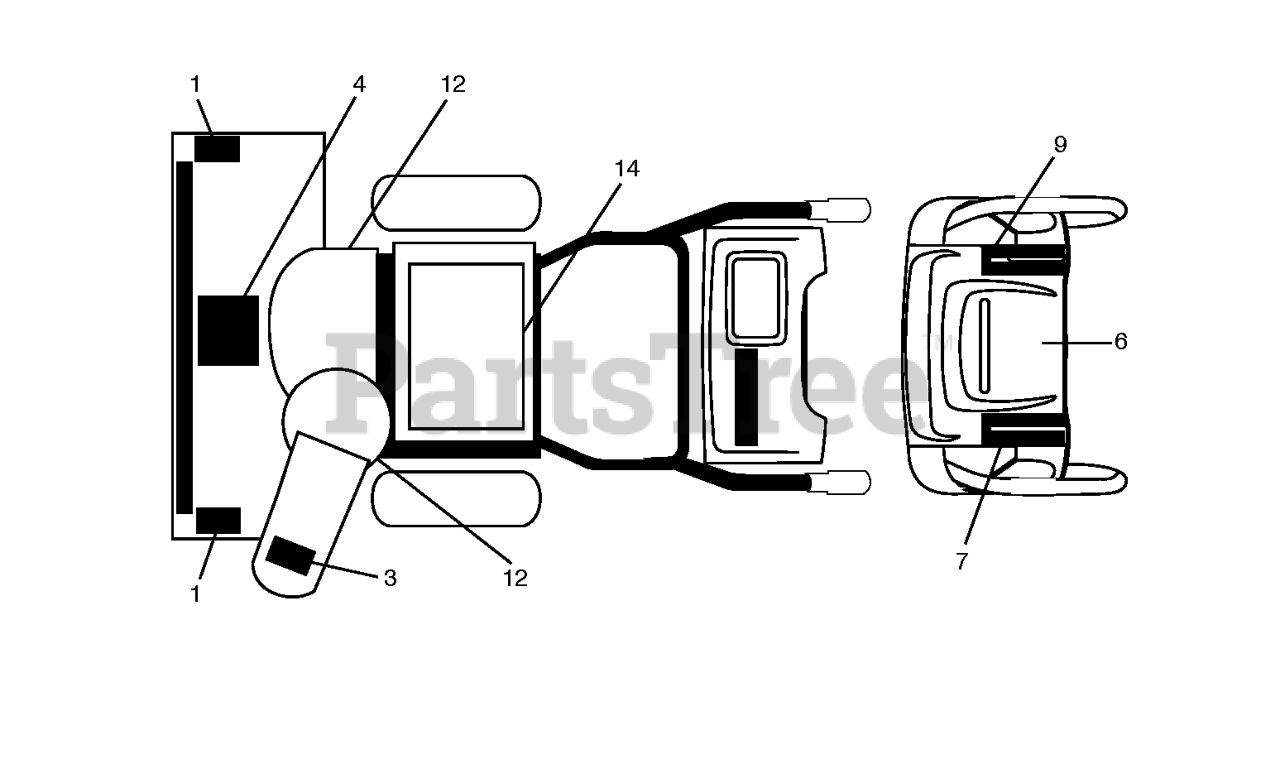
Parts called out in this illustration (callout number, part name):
1	DECAL.AUGER.SAFETY.
3	DECAL.CHUTE.SAFETY.
4	DECAL.AUGER."
7	DECAL.CONS.LT.SPD/LEV/PWRST.
9	DECAL.CONS.RT.SPD/LEV/PWRST.
12	DECAL.BELT.GUARD.
14	DECAL.FENDER
